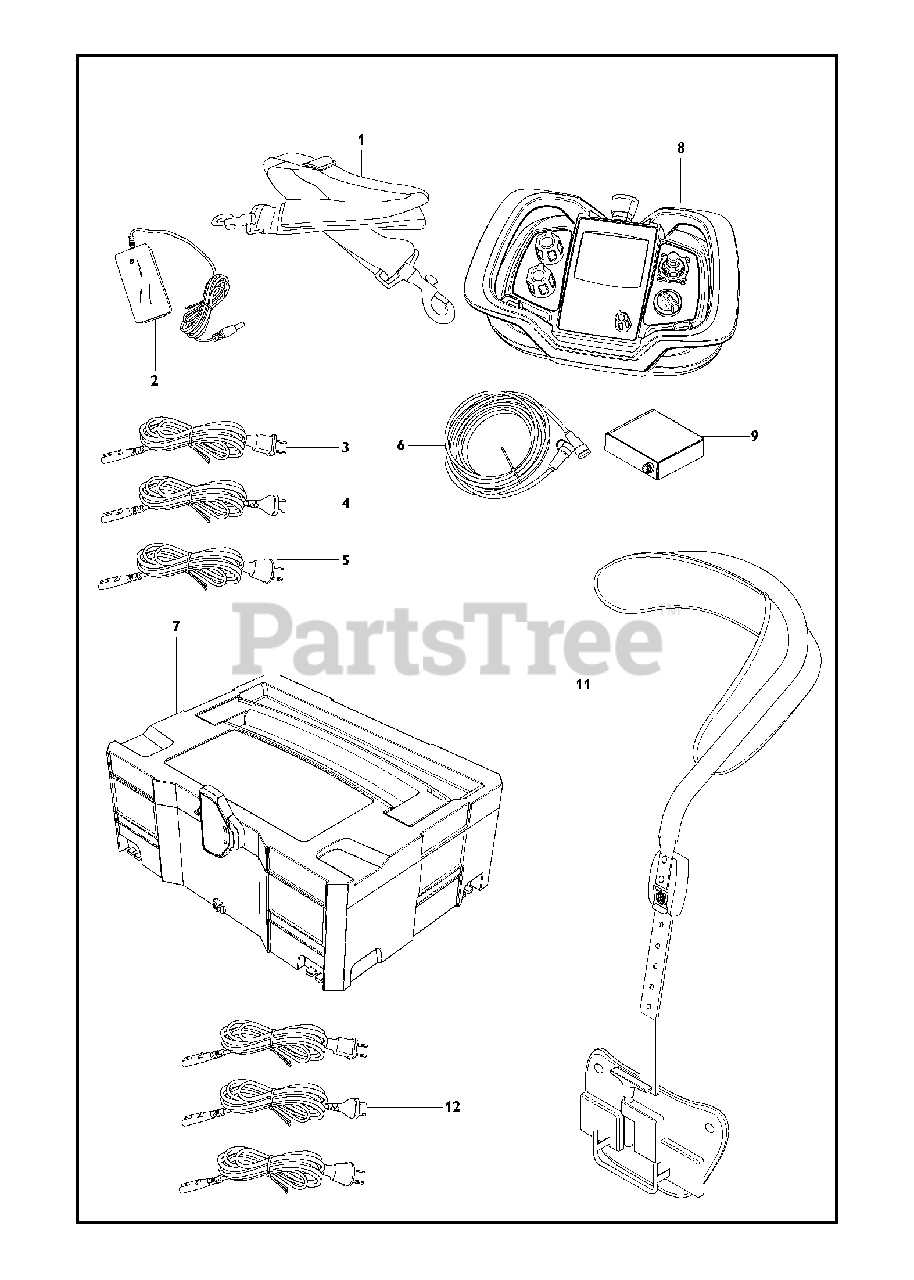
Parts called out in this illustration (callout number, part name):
12	CABLECABLE MACHINE EU, 4 M
12	CABLECABLE MACHINE US, 4 M
12	CABLECABLE MACHINE AU, 1,8 M
